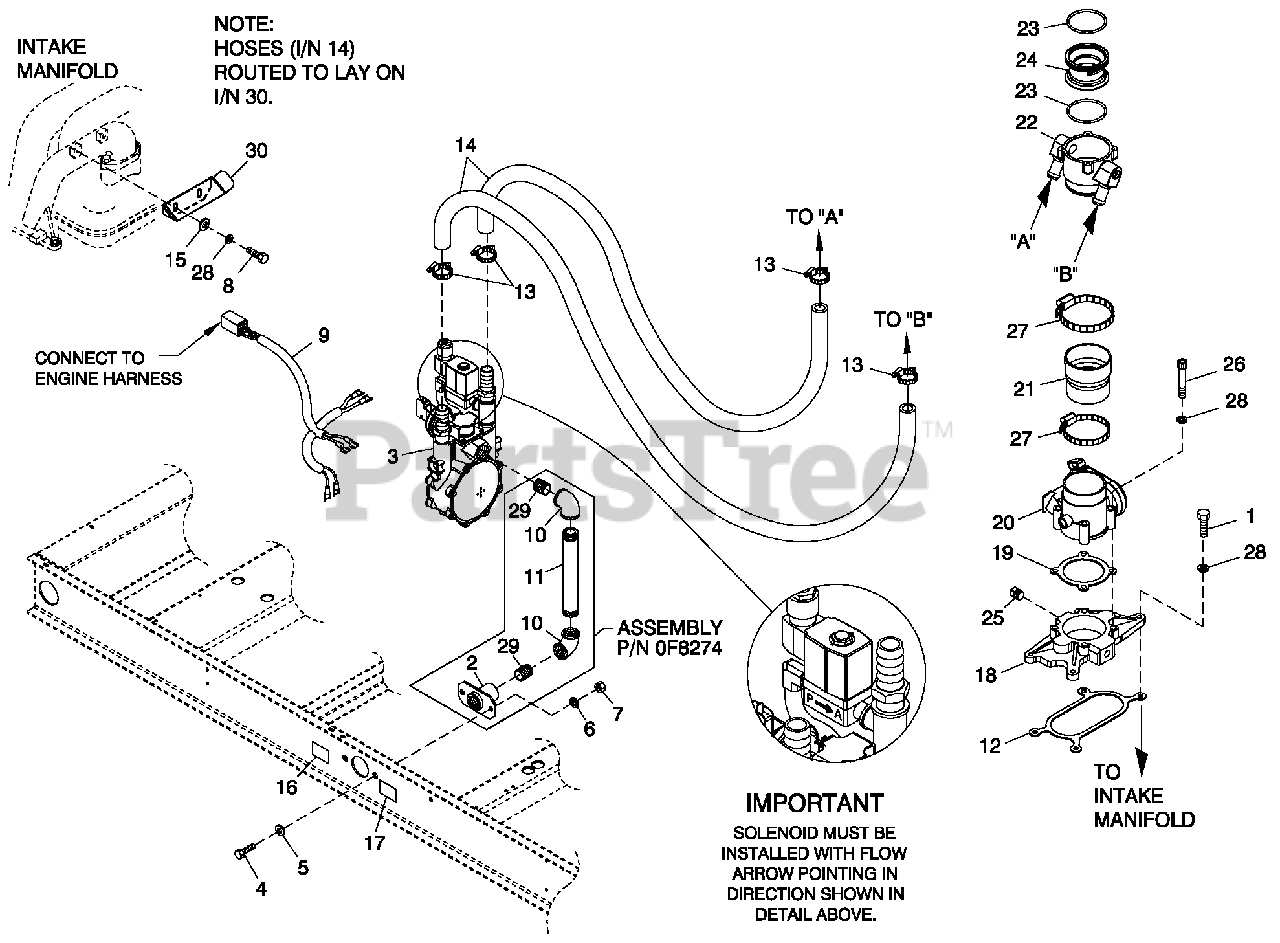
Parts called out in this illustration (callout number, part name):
1	SCREW HHC M6-1.0 X 35 G8.8 BLK
2	FLANGE FUEL INLET
3	REG ASSY 6.8L 70KW LPV CPL
4	SCREW HHC M8-1.25X 20 G8.8
5	WASHER FLAT 5/16-M8 ZINC
6	WASHER LOCK M8-5/16
7	NUT HEX M8-1.25 G8 CLEAR ZINC
8	SCREW HHC M6-1.0X 20 G8.8
9	HARNESS,FUEL JUMPER SINGLE REG
10	ELBOW 90D 3/4NPT
11	NIPPLE PIPE 3/4NPT X 7
12	GASKET ADAPTER THROT BODY
13	CLAMP HOSE #10 .56-1.06
14	HOSE 3/4 ID SAE-30R2 (38.5" LG)
15	WASHER FLAT M6
16	DECAL INLET PRESSURE
17	DECAL FUEL INLET NG (NATURAL GAS APPLICATION)
18	ASSY,ADAPTER,THROTTLE BODY
19	GASKET, GOVERNOR ACTUATOR
20	ACTUATOR BOSCH 60, GOVERNOR
21	REDUCER 3.0" TO 2.75" TURBO
22	MIXER, 40/60MM ACTUATOR ASSY
23	O-RING 2 -3 /4X 3 /3 2X 2 -1 5 /1 6
24	VENTURI, THROTTLE 36MM
25	PLUG STD PIPE 1/4 STEEL SQ HD
26	SCREW SHC M6-1.0 X 50 C8.8
27	CLAMP HOSE #44 2.31-3.25
28	WASHER LOCK M6-1/4
29	NIPPLE CLOSE 3/4X1.375
30	BRACKET, HOSE RISER
